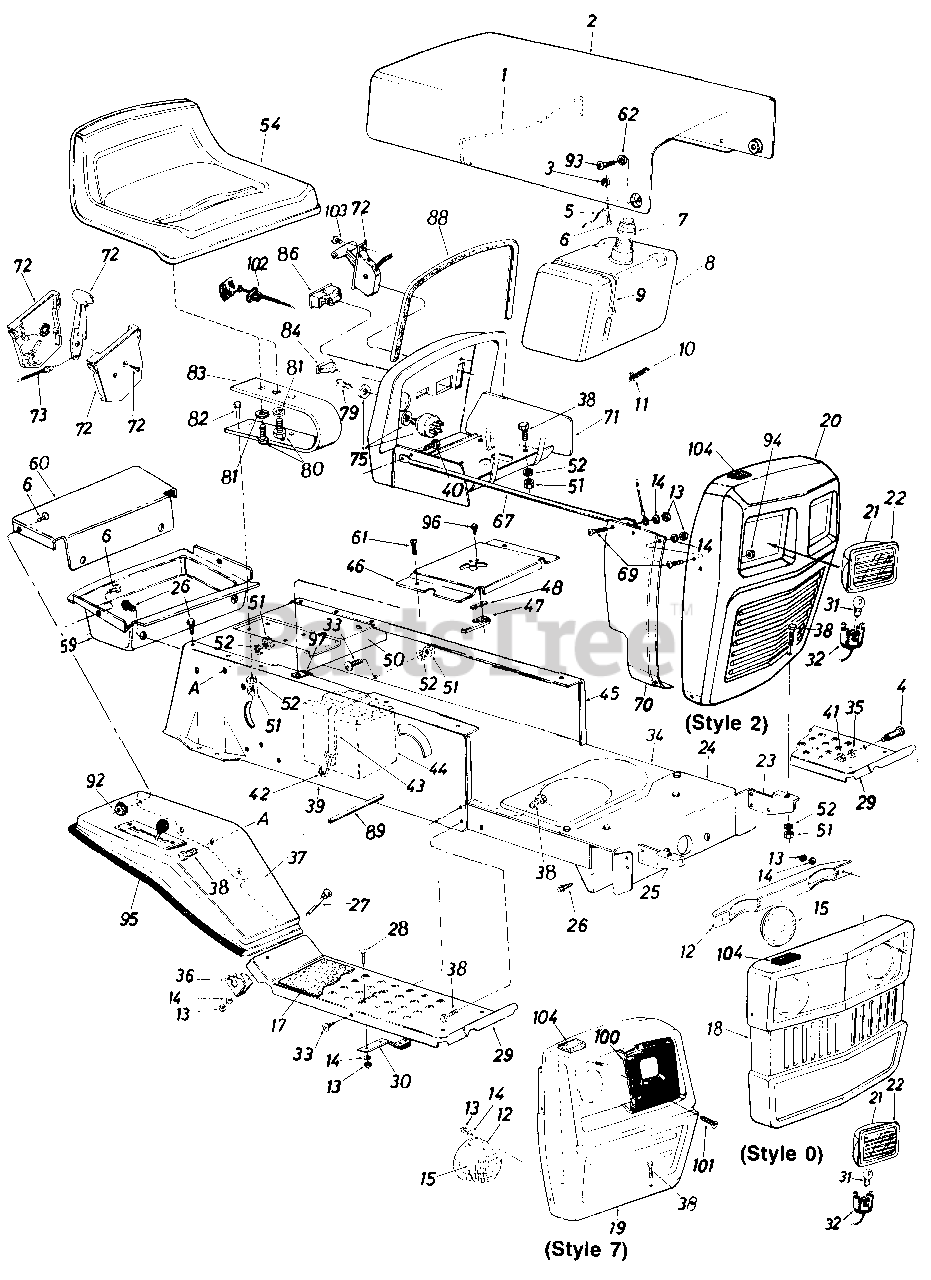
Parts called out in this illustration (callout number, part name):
1	Hood Spring
2	Hood
3	Hex Sems Nut #10-24 Thd.
4	Shld. Bolt .50 Dia. x .84
5	Hood Stop 7" Lg.
6	Truss Hd. Scr. #10-24 x 1/2"*
7	Fuel Cap Gauge
8	Fuel Tank
9	Tie Strap
10	Fuel Line
11	Hose Clamp
12	Headlight Retainer [Used with Grille Ref No. 18
13	Hex Nut 1/4-20 Thd.*
14	L-Wash. 1/4" I.D.
15	Headlight
17	Foot Pad
18	Grille-Round Lights
22	Headlight Lens
23	Grille Mount Brkt.-L.H.
24	Front Pivot Brkt.
25	Grille Mount Brkt.-R.H.
26	Hex Wash. Hd. AB-Tap Scr. 5/16 x .75" Lg.
27	Carriage Bolt 1/4-20 x 2.0"*
28	Carriage Bolt 1/4-20 x .62"*
29	Running Board
30	Blade Brake Ass'y.
31	Head Lamp
32	Twist Lock Lamp Socket
33	Truss Mach. Scr. 5/16-18 x .75" Lg.*
34	Lower Frame
35	L-Wash. 3/8" I.D.
36	Fender Clamp
37	Fender
39	R.H. Side Fram
40	Hex Bolt 1/4-20 x .62" Lg.
41	Hex Nut 3/8-16 Thd.
42	Battery Strap Hook
43	Battery Hold Down Strap
44	12-V Battery
45	I.H. Side Fram
46	Shift Cover
47	Reverse Safety Switch
48	Insulator Nut Plate
50	Hitch Plate
51	Hex Nut 5/16-18 Thd.
52	L-Wash. 5/16" I.D.*
54	Seat Ass'y.
59	Tool Tray
62	Washer .39" I.D. x .62"
67	Grille Support Rod
69	Truss Hd. Scr. 1/4-20 x .75"*
70	R.H. Grille Side Panel
71	Dash Panel Ass'y.
72	Throttle Control Box Ass'y.
73	Throttle Control Wire-B&S
75	Ignition Switch
79	Ignition Key
80	Hex Bolt 1/2-13 x 1.00" Lg.
81	L-Wash. 1/2" I.D.
82	Hex Bolt 5/16-18 x 1.0"*
83	Seat Spring 5.5" High
84	Light Switch
86	Ammeter
88	Molding Strip 27" Lg.
89	Running Board Rod
92	Hex Sems Nut #10-24 Thd.
93	Shld. Bolt .375 Dia. x .125
94	L-Nut 1/4-28 Thd.
95	Trim Strip-57" Lg.
96	Hex Wash. Hd. AB-Tap Scr. #8 x .50" Lg.
97	Speed Nut #10Z
100	Bezel
101	Hex Wash. F-Tap Scr. #8 x . 38"
102	Choke Control 29" Lg.
103	Truss Mach. AB-Tap Scr. #10 x .50" Lg.
104	Foam Strip 3/8 x 1-1/8 x 11/2
